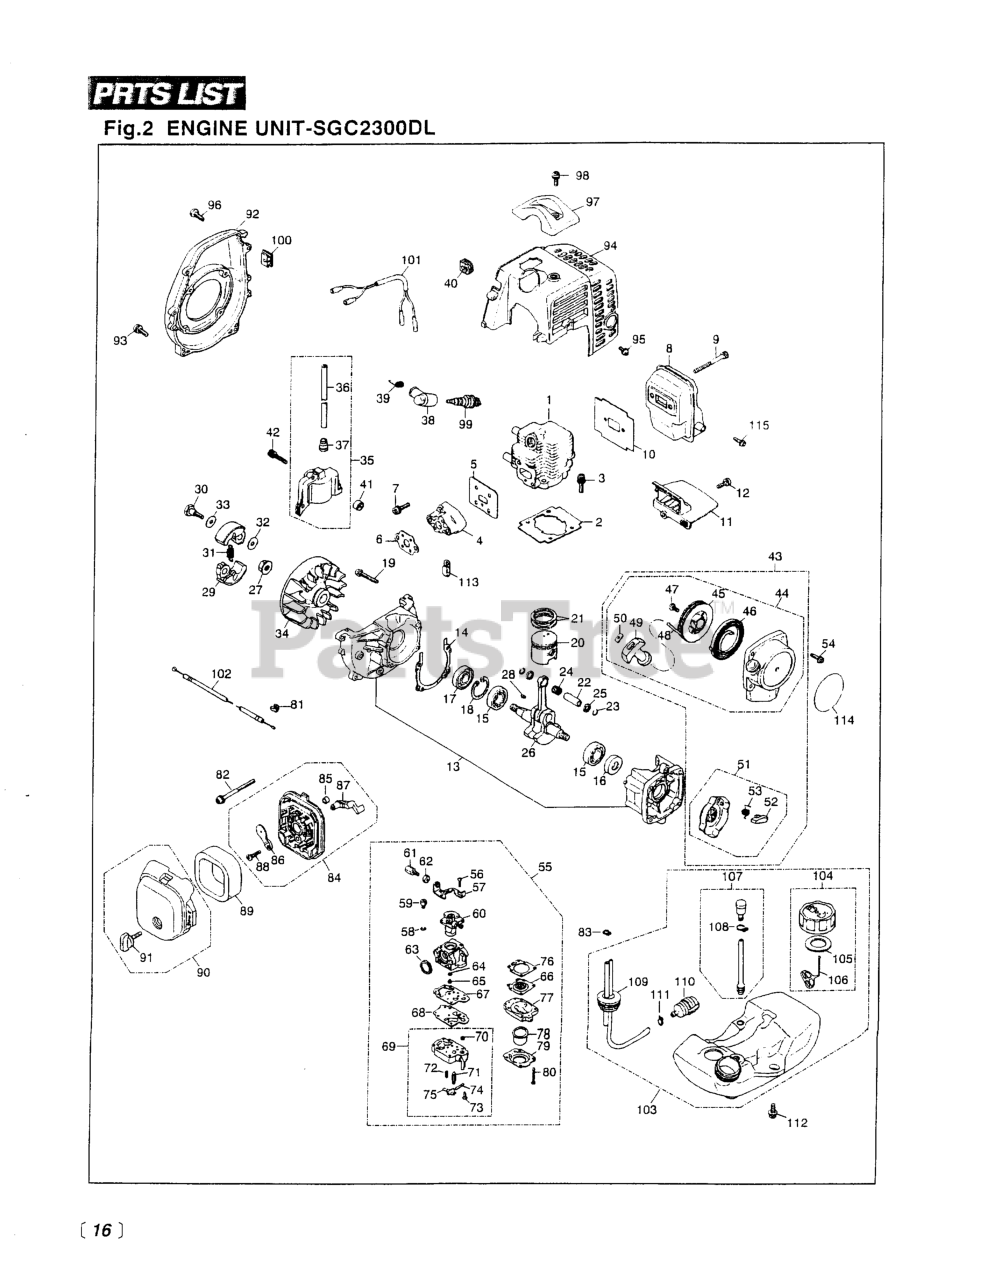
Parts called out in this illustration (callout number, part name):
1	CYLINDER
3	BOLT, M5 X 22
7	SCREW, M5X20 (RPLS.1400-75510)
8	MUFFLER ASSY (USE 5913-15100)
9	BOLT, M5 x 50
10	GASKET, MUFFLER
12	SCREW, M4 X 16
13	CRANKCASE
15	BEARING
16	SEAL, OIL (RPLS 1100-21210)
17	SEAL, OIL (RPLS 1140-21220)
18	RING, SNAP, M28 x 1.2
19	BOLT, M5 X 30
20	PISTON (REPLACES 1140-41110)
21	RING, PISTON (RPLS 1850-41210)
22	PIN, PISTON 5x8x26
23	RING, SNAP (RPLS 1101-41320)
25	WASHER
26	CRANKSHAFT (RPLS 1850-42000)
28	KEY
30	BOLT
31	SPRING, CLUTCH (RPLS-51220)
32	WASHER, FLAT (USE 182303)
34	ROTOR (SGC2300)
36	CORD
37	CAP
39	SPRING
40	GROMMET
41	SPACER (RPLS -71260)
42	BOLT
44	RECOIL ASSEMBLY
45	REEL
46	SPRING, SPIRAL
47	SCREW (RPLS -75150)
49	KNOB
50	PLATE, STOPPER
51	PULLEY ASSY (RPLS -75210)
52	RATCHET (RPLS 1850-75220)
53	SPRING, RETURN
54	SCREW, M4 X 16
55	CARBURETOR (WYJ-114-1)
56	SCREW
57	BRACKET
58	RING
59	SWIVEL
60	VALVE ASSEMBLY
61	SCREW, CABLE ADJUSTER
62	NUT, CABLE ADJUSTER
63	RING, PACKING
64	RING, O
66	DIAPHRAGM (USE 4810-81260)
67	GASKET, PUMP
68	DIAPHRAGM
69	BODY, PUMP
71	VALVE, INLET
73	SCREW, METERING LEVER PIN
74	PIN, METERING LEVER
75	LEVER
76	GASKET, DIAPHRAGM
77	BODY, PURGE
78	PUMP, PRIMING
79	COVER, PUMP
80	SCREW
81	CAP, CABLE END
82	SCREW, M5 x 60
83	CLIP
85	SLEEVE
86	PLATE, CHOKE (RPLS-82130)
87	LEVER, CHOKE
88	SCREW (REPLACES 50030272)
89	ELEMENT
91	KNOB (RPLS -82220)
92	COVER, FAN (RPLS-31110)
93	SCREW, M5X20 (RPLS.1400-75510)
95	SCREW, M5 x 12
96	SCREW, HOUSING
97	GUARD, PLUG
98	SCREW,M5 X 14 (RPLS 1400-15510
101	CORD COMP (RPLS -73200)
102	CABLE COMP (RPLS 1633-83100)
104	CAP (RPLS -85200)
105	PACKING
108	CLIP
109	PIPE COMPLETE
110	FILTER ASSY
111	CLIP (REPLACES 2841-31280)
112	SCREW
113	CLAMP
114	LABEL, RECOIL
115	ARRESTER (RPLS 5850-15140)
